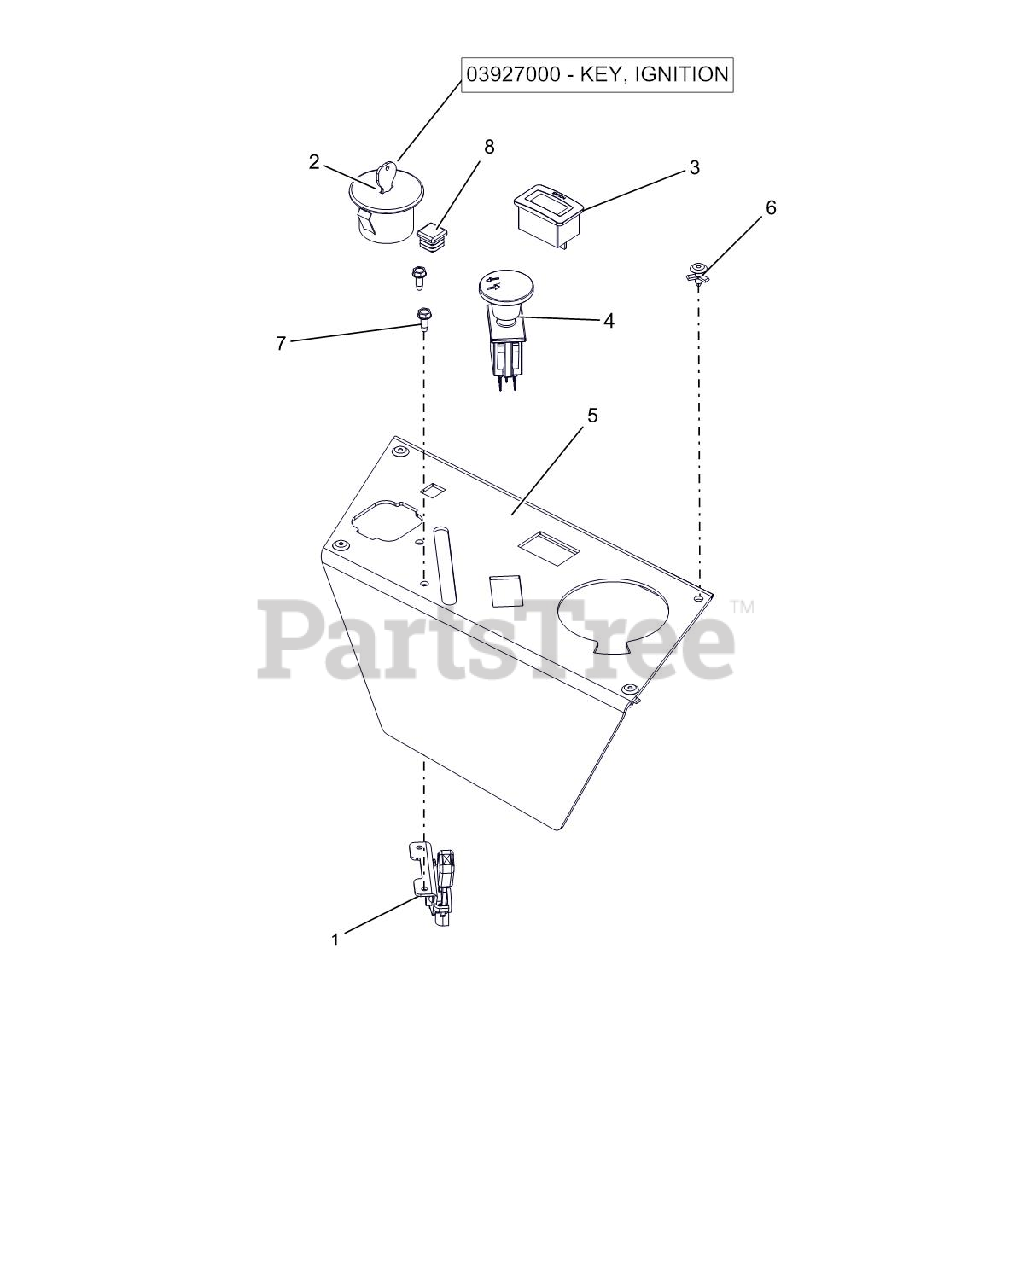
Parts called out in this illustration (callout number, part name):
1	CABLE - THROTTLE CONTROL
2	KEY, 03290500 KEYSWITCH
3	KEYSWITCH-IGNITION 4 POS
3	KEYSWITCH-IGNITION 3 POS
3	HOUR METER
4	SWITCH, CLUTCH (YELLOW)
5	PANEL, CONTROL
6	RIVET, PLASTIC .195 DIA.
7	@SCR-TAP 10-24X.50 HWH TR YWZC
8	PLUG, 5/8" SQ BLACK (14-20GA)
